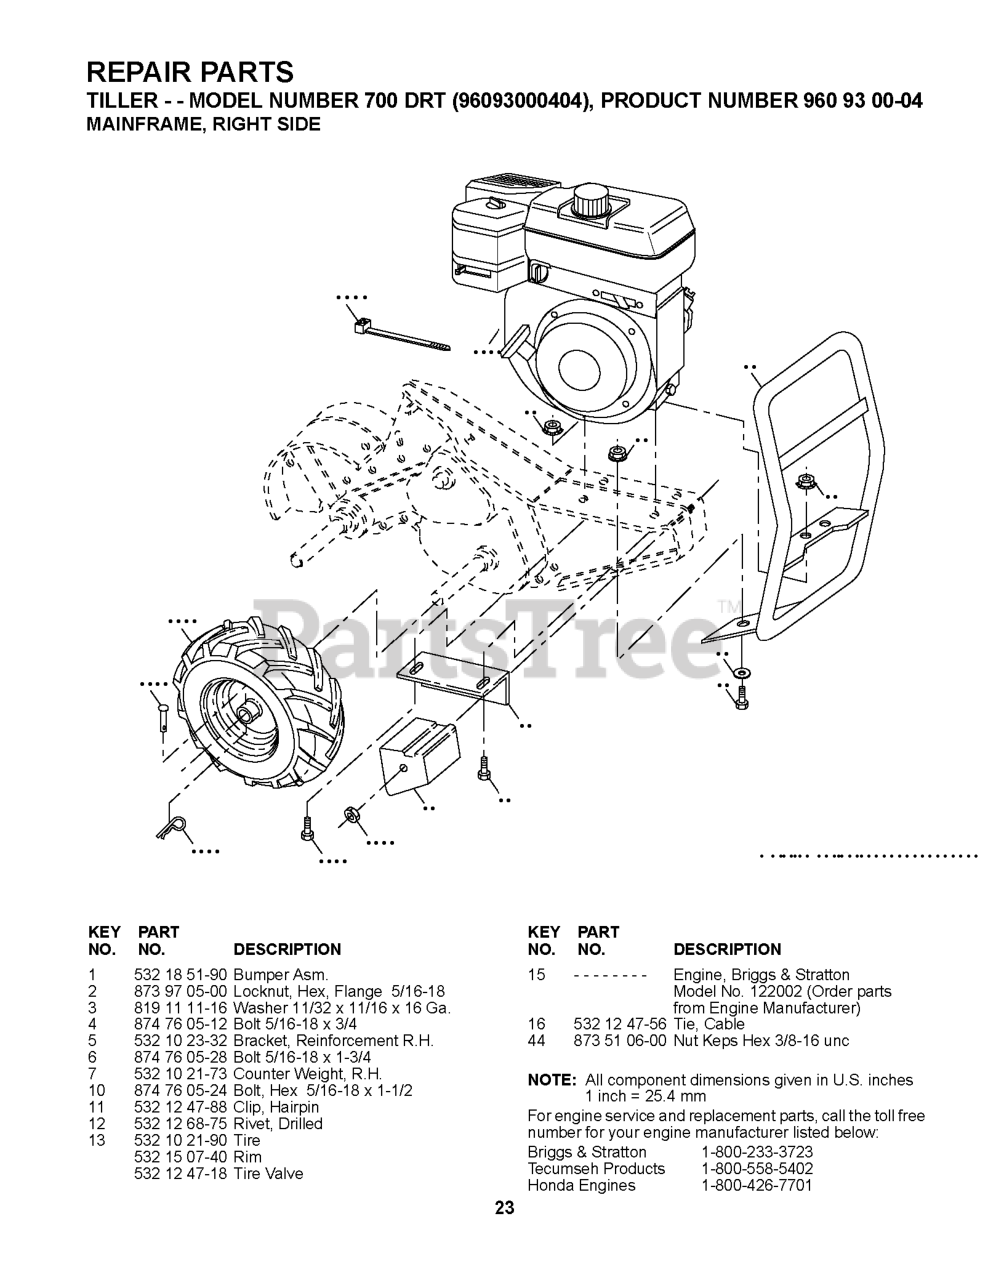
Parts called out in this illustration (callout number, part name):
1	RP.BUMPER.ASM.TILLER.
2	LOCKNUT-FLANGE 5/16-18
3	WASHER
4	BOLT
5	DNO BRACKET RH CRT
6	BOLT, HEX 5/16-18X1-3/4
7	COUNTERWEIGHT, RH
10	BOLT
11	RETAINER M
12	RIVET,DRILLED
13	TIRE.13X5-6.CHEVRON.TILLER
16	TIE GUIDE
